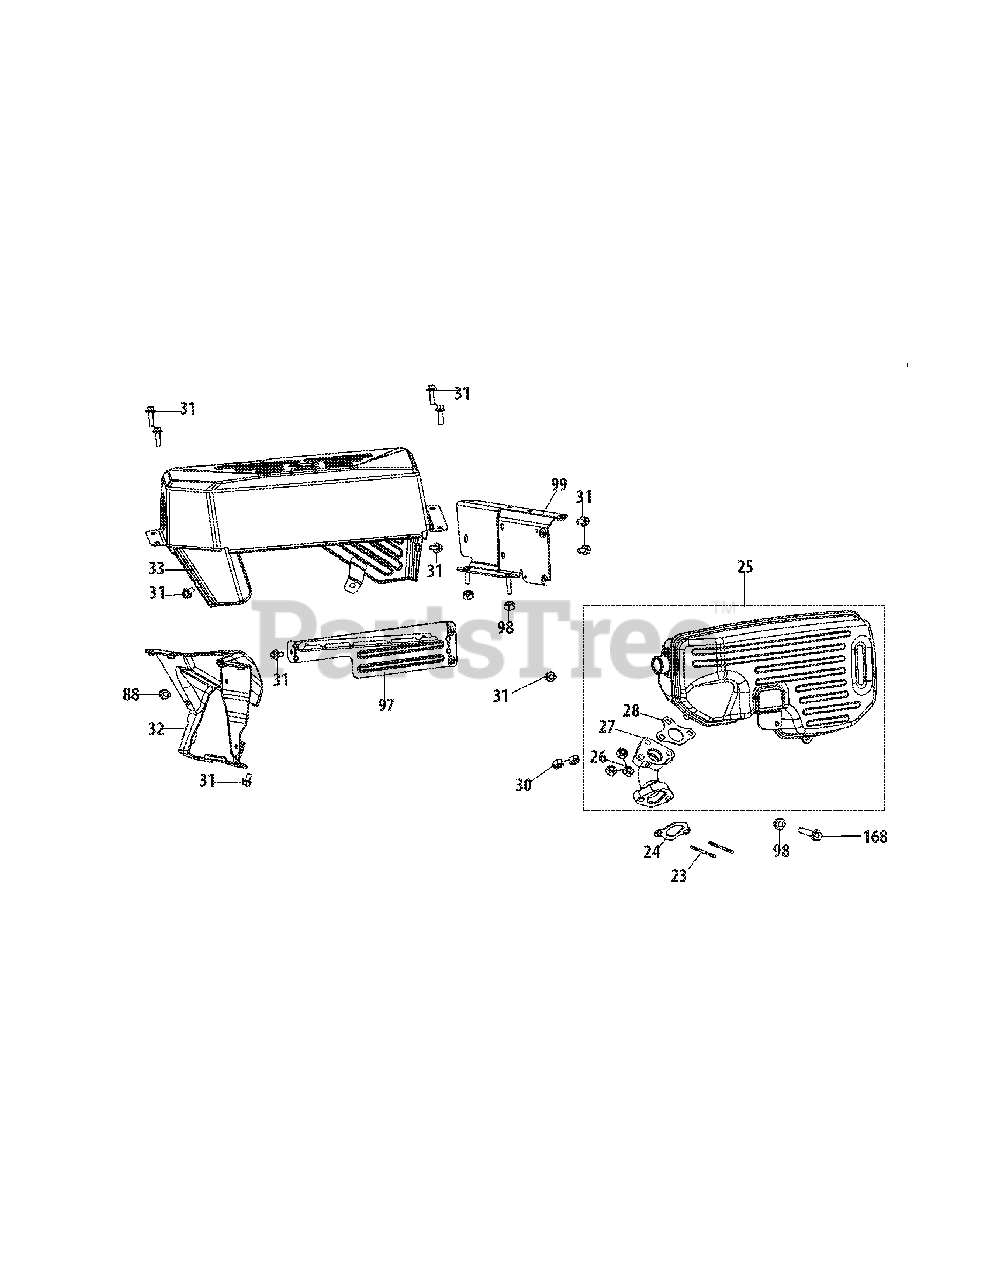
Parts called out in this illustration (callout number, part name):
23	Stud, M8×36
24	Gasket, Muffler
25	Muffler
26	Nut, M8
27	Exhaust Pipe
28	Gasket, Muffler
30	Nut, M8
31	Bolt, M6×12
32	Front Bracket, Fuel Tank
33	Muffler Guard
88	Bolt, M8×32
97	Fuel Tank Insulator
98	Nut, M6
99	Fuel Tank Base
168	Bolt, M6×20
